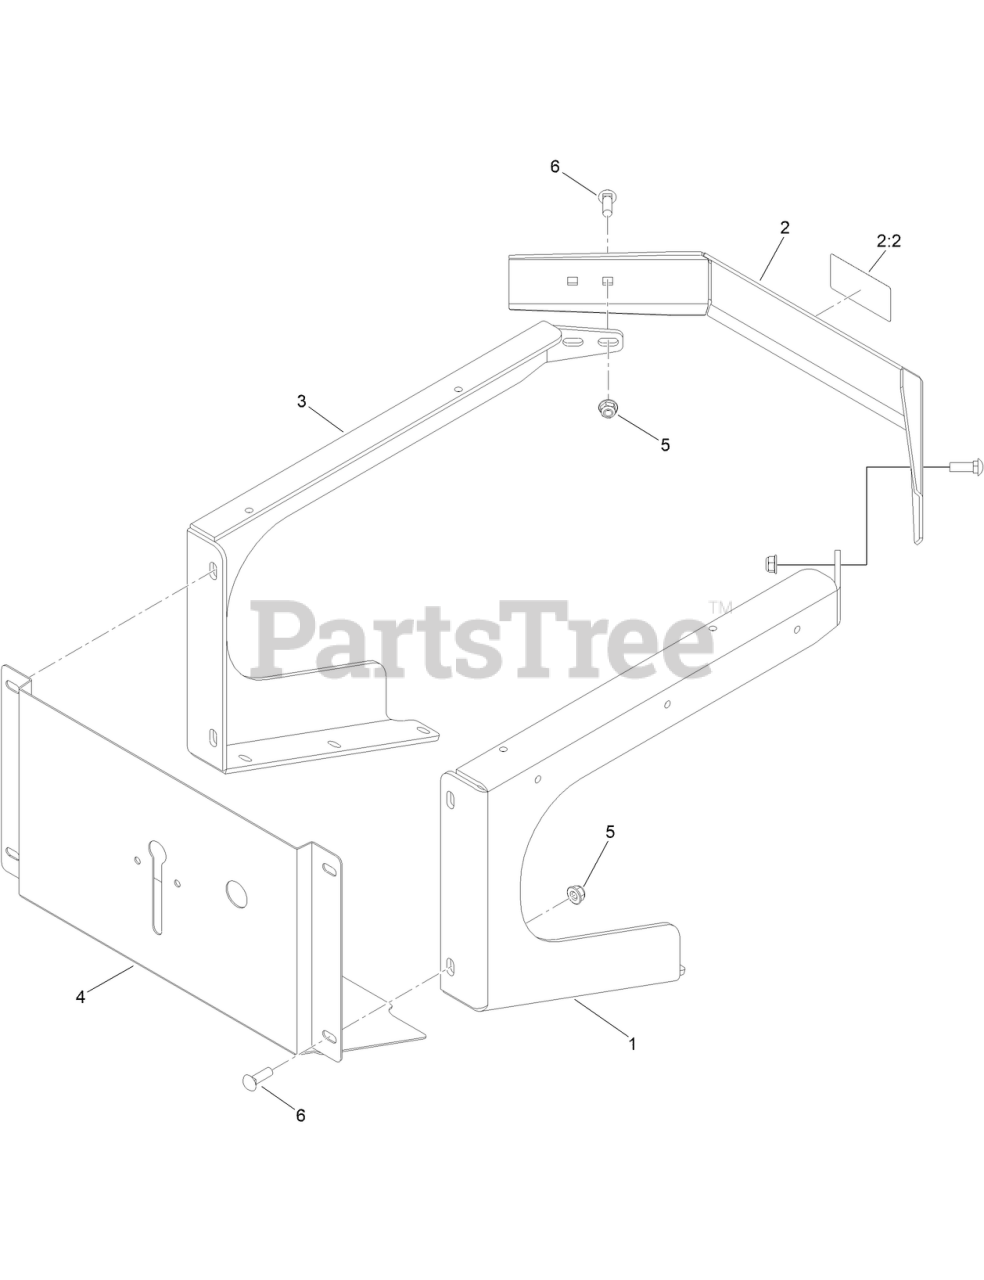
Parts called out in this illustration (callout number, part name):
1	FRAME-HOPPER, RH
2	Hopper Bumper ASM W/Decal
2:2	Decal-Dismemberment Hazard
3	FRAME-HOPPER, LH
4	BACKSHIELD, HOPPER, SS, 0.06
5	Nut-Hex Flange
6	Bolt,Carriage,5/16-18X1,ST/ST 18-8
